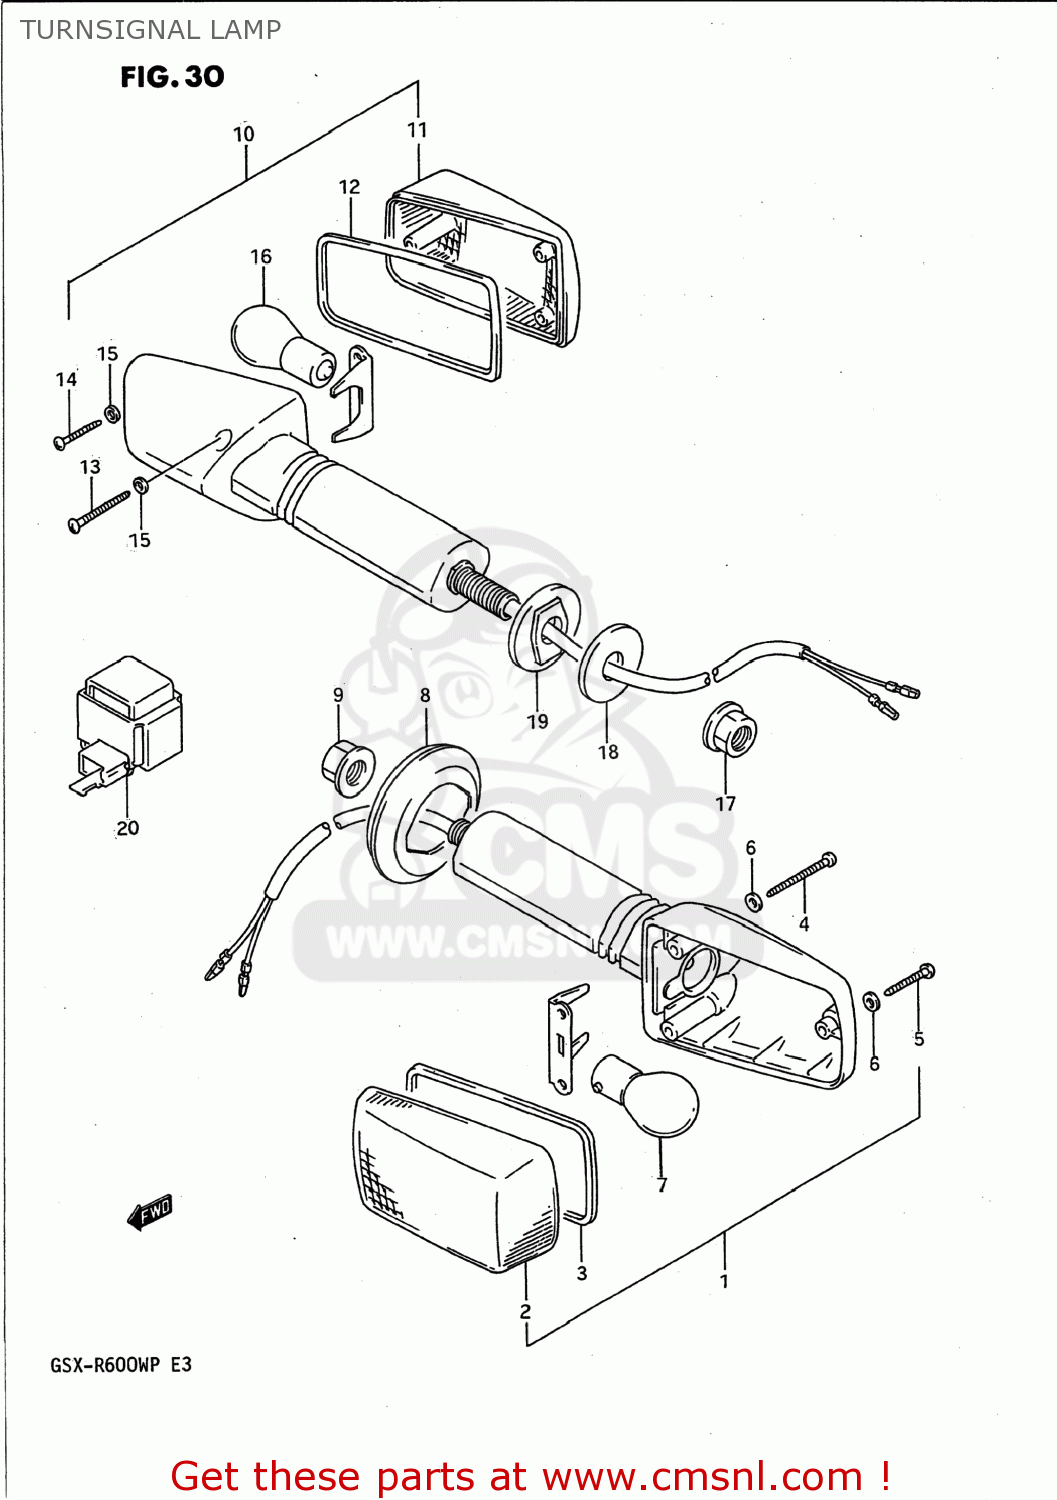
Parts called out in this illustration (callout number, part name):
1	LAMP ASSY,FR TURN SIGNAL
2	LENS
3	GASKET (NAS)
4	SCREW(3X30)
5	SCREW
6	GASKET (NAS)
7	BULB(12V21W)
8	GROMMET
9	NUT
10	LAMP ASSY,FR TURN SIGNAL
11	LENS
12	GASKET (NAS)
13	SCREW(3X30)
14	SCREW
15	GASKET (NAS)
16	BULB(12V21W)
17	NUT
18	WASHER(10.5X30X3.2)
19	SPACER,RR TURNSIGNAL
20	RELAY,TURN SIGNAL
